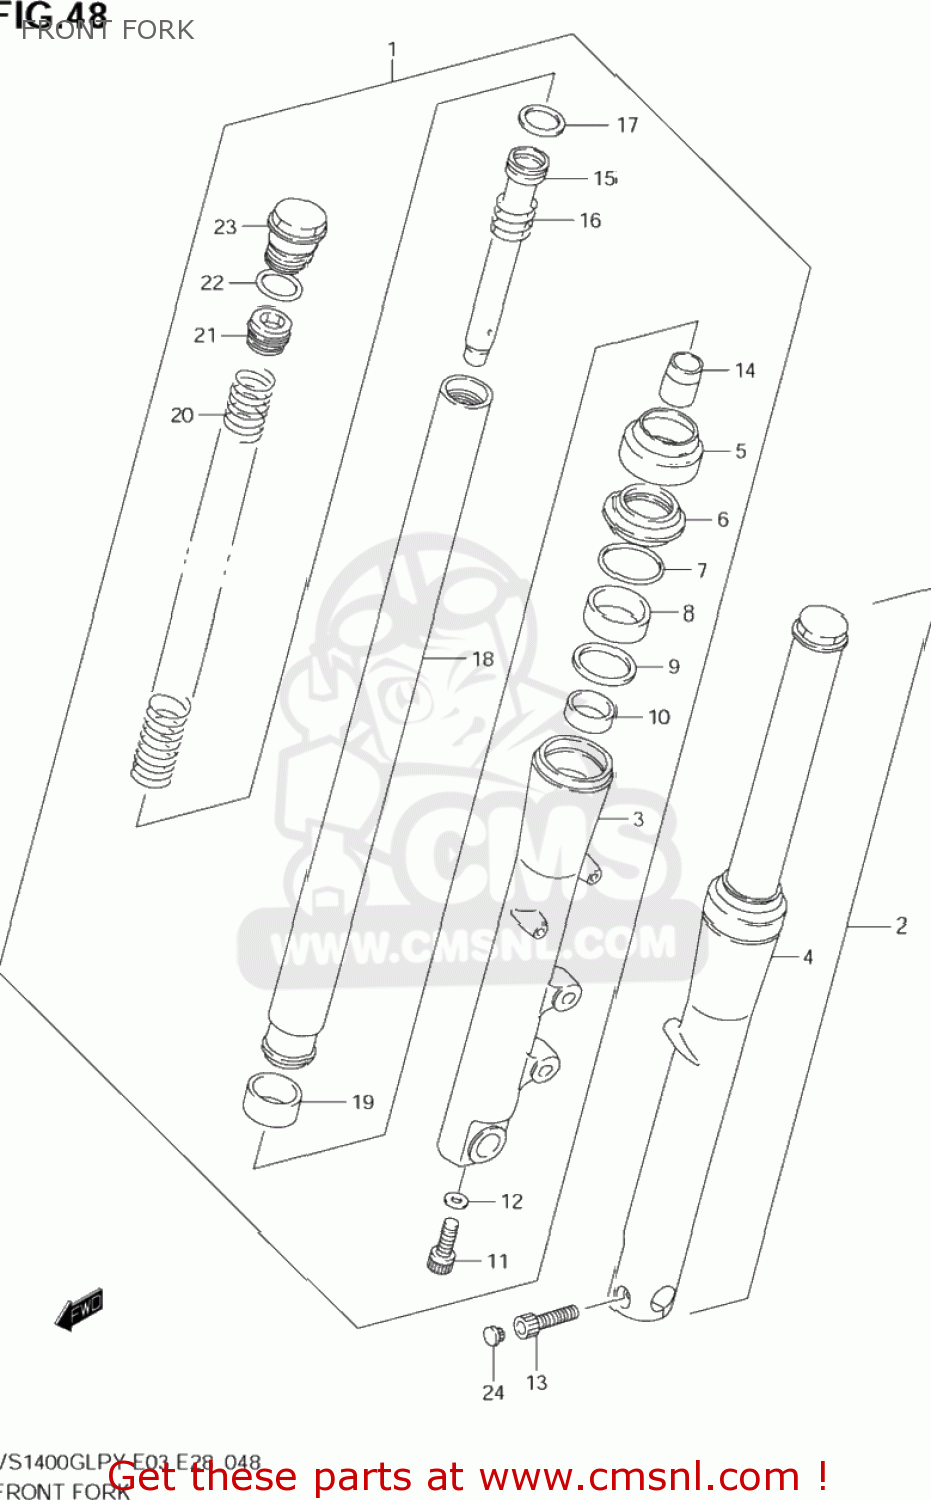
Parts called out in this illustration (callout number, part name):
1	DAMPER ASSY,FR FORK,R
2	DAMPER ASSY,FR FORK,L
3	TUBE,OUTER,R
4	TUBE,OUTER,L
5	COVER,CASE
6	DUST SEAL
7	CIRCLIP,FORK OIL SEAL
8	SEAL,OIL
9	SPACER,SEAL
10	BUSH,GUIDE
11	BOLT(8X27)
12	GASKET (NAS)
13	BOLT
14	PIECE,OIL LOCK
15	CYLINDER
16	SPRING,REBOUND
17	RING,PISTON
18	TUBE,INNER
19	BUSH,SLIDE
20	SPRING,FR FORK
21	BOLT,FORK INNER
22	O RING
23	BOLT
24	CAP(OD:14.5)
